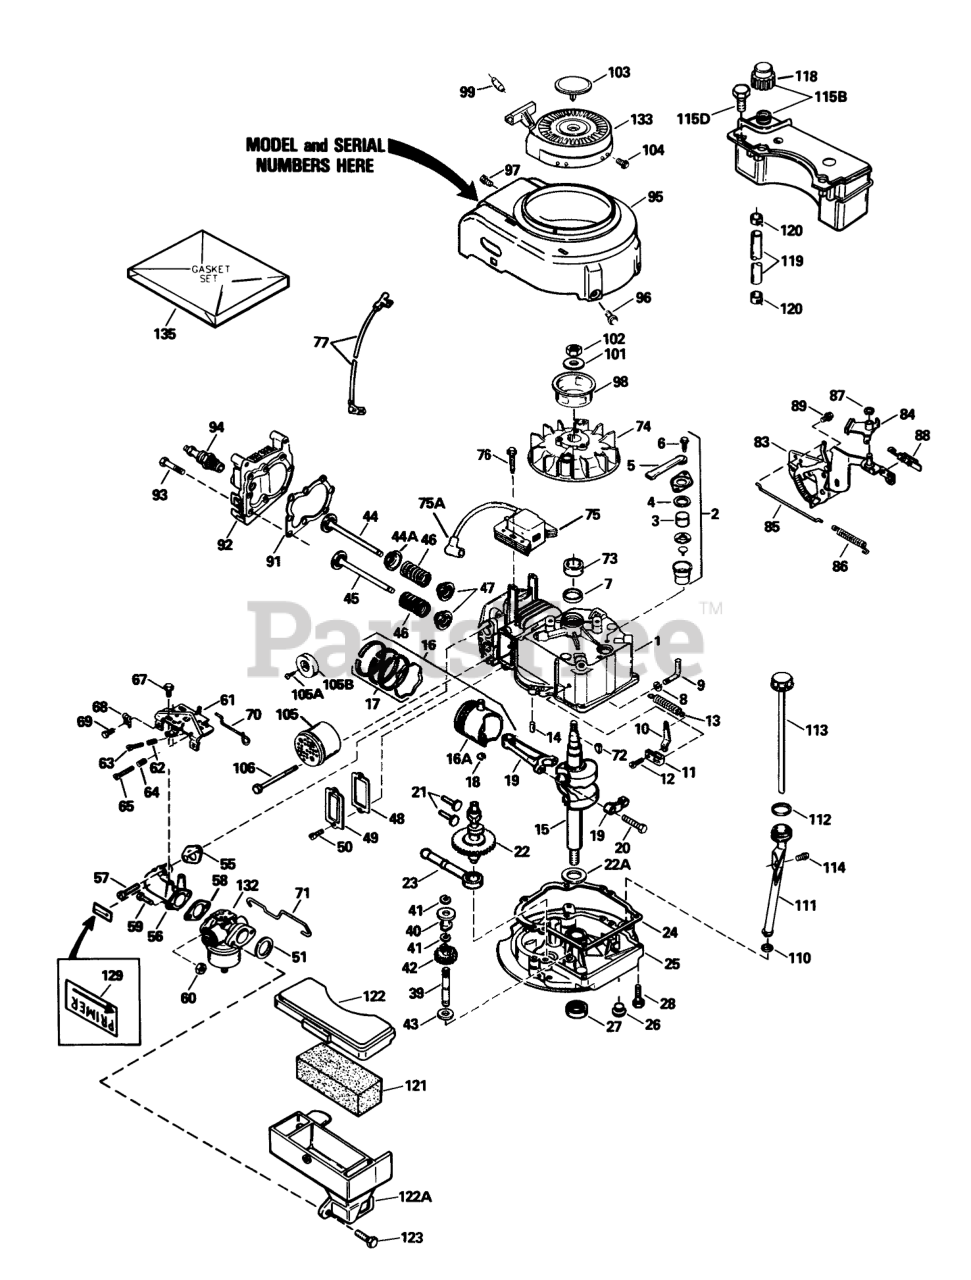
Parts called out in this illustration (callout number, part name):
1	Cylinder Assy. (Incl. Ref. #7 & 14)
2	Breather Assy. (Incl. Ref. #3, 4, 5 & 6)
3	Element-Breather
4	Gasket-Breather
5	Tube, Breaker
6	Screw (10-24 x 9/16)
7	Seal-Oil
8	Washer-Flat
9	Rod, Governor (Incl. Ref. #8)
10	Governor Lever
11	Clamp-Lever, Governor
12	Screw
13	Spring Governor
14	Pin-Dowel
15	Crankshaft
16	Piston, Pin & Ring Assy. (STD.) (Incl. Ref. #16A, 17&18)
16	Piston, Pin & Ring Assy. (.010 oversize) (Incl. Ref. #16A, 17 & 18)
16	Piston, Pin & Ring Assy. (.020 oversize)(Incl. Ref. #16A, 17 & 18)
16A	Piston & Pin Assy. (Std.) (Incl. Ref. #18)
16A	Piston & Pin Assy. (.010 oversize) (Incl. Ref. #18)
16A	Piston & Pin Assy. (.020 oversize) (Incl. Ref. #18)
17	Ring Set-Piston (Std.)
17	Ring Set, Piston(.0100versize)
17	Ring Set (.020" OS)
18	Ring-Retaining, Piston Pin
19	Rod Assy., Connecting (Incl. Ref. #20)
20	Bolt-Rod, Connecting
21	Lifter-Valve
22	Camshaft (Mech.Compression Release)
22A	Washer-Thrust
23	Oil Pump ASM
24	Gasket
25	Flange, Mounting (Incl. Ref. #26, 27 & 39)
26	Plug Oil Drain
27	Seal-Oil
28	Screw (1/4-20 x 1-1/4)
39	Shaft-Governor
40	Spool-Governor
41	Ring-Retaining
42	Gear Assy., Governor (Incl. Ref. #43)
43	Washer
44	Valve, Intake (Std.) (Incl. Ref. #47)
44	Valve, Intake (1/32" oversize)(Incl. Ref. #47)
44A	Seal Assy., Intake
45	Valve, Exhaust (Std.) (Incl. Ref. #47)
45	Valve, Exhaust (1/32"oversize) (Incl. Ref. #47)
46	Spring-Valve
47	Cap-Valve, Spring
48	Gasket-Cover, Valve
49	Cover-Valve
51	Gasket-Cleaner, Air
55	Gasket-Intake Pipe
56	Pipe, Intake (Incl. Ref. #55)
57	Screw (1/4-20 x 1)
59	Screw (1/4-28 x 7/8)
60	Nut and Lock Washer (1/4-28)
61	Bracket Assy., Control (Incl. Ref. #62 thru 65)
62	61709/GIL1515A/95-5
63	Screw
64	Spring-Compression
65	Screw
67	Screw (10-24 x 9/16)
68	Conduit
69	Screw (10-32 x 3/8)
70	2035A67 ADD.ASSEMBL
71	Link-Throttle
72	Key-Flywheel
74	Flywheel
75	Solid State
75A	Cover-Spark Plug
76	Screw
77	Ground Wire
83	Bracket-S.E. Brake
84	Lever-Brake
85	Link-Control
86	Spring-Extension
87	Ring-Retaining
88	Terminal
89	Screw (1/4-20 x 3/8)
91	Gasket-Cylinder Head
92	Head-Cylinder
93	Screw (5/16-18x1-1/2)
94	Spark Plug-Resistor (R J19 L M)
95	Housing-Blower
96	Screw (1/4-20 x 1/2)
97	Screw (10-24 x 9/16)
98	Hub-Starter
99	Retainer-Starter Rope
101	Washer-Belleville
102	Nut-Flywheel
103	Plug Starter
104	Screw, Hex Hd.
105	Muffler Assy. (Incl. Ref. #106)
105A	Cover-Muffler
105B	Screw (8-32 x 3/8)
111	Oil Fill Tube
113	Dipstick
114	Screw (10-32 x 1/2)
115B	Tank Assy. (Incl. Ref. #118 & 120)
115D	Screw (10-32 x 35/64)
118	Cap-Fuel
119	Line-Fuel
120	Clamp-Line, Fuel
121	Filter-Air Cleaner
122	Cover-Air Cleaner
122A	Body Air cleaner
129	Decal-Primer
132	Carburetor (Incl. Ref. #58)
133	Starter-Rewind
135	Gasket Set (Incl. items marked )
